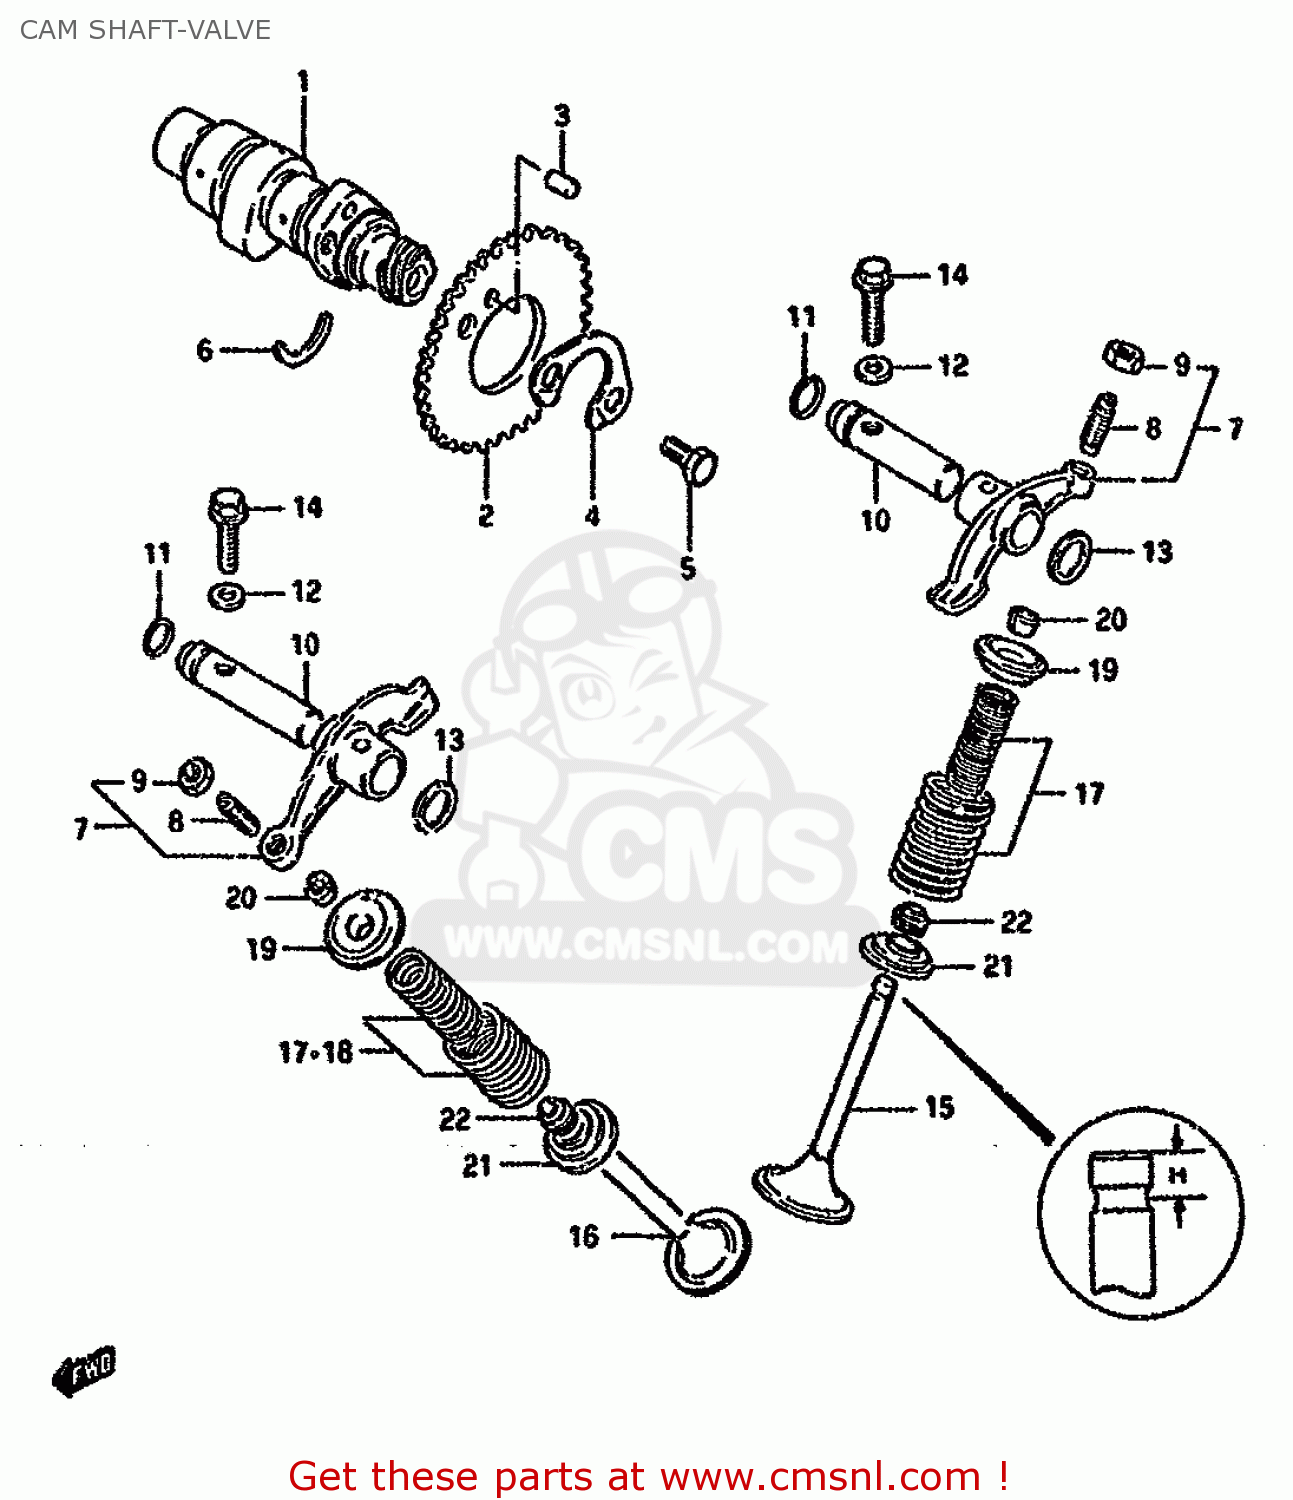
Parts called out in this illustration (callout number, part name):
1	CAMSHAFT
2	SPROCKET,CAMSHAFT
3	PIN(5X8)
4	WASHER,SPROCKET
5	BOLT(6X10.5)
6	C RING
7	ARM ASSY,VALVE ROCKER
8	SCREW,TAPPET ADJUSTING
9	NUT,ADJUSTING SCREW
10	SHAFT,VALVE ROCKET
11	O RING(D:1.9,ID:8.6)
12	GASKET(5.8X13X1.2) (NAS)
13	WASHER
14	BOLT
15	VALVE,INTAKE
16	VALVE,EXHAUST
17	SPRING SET,VALVE
18	SPRING SET,VALVE
19	RETAINER,VALVE SPRING
20	COTTER VALVE
21	SEAT,VALVE SPRING
22	SEAL,OIL(5.5X11X8.2)
